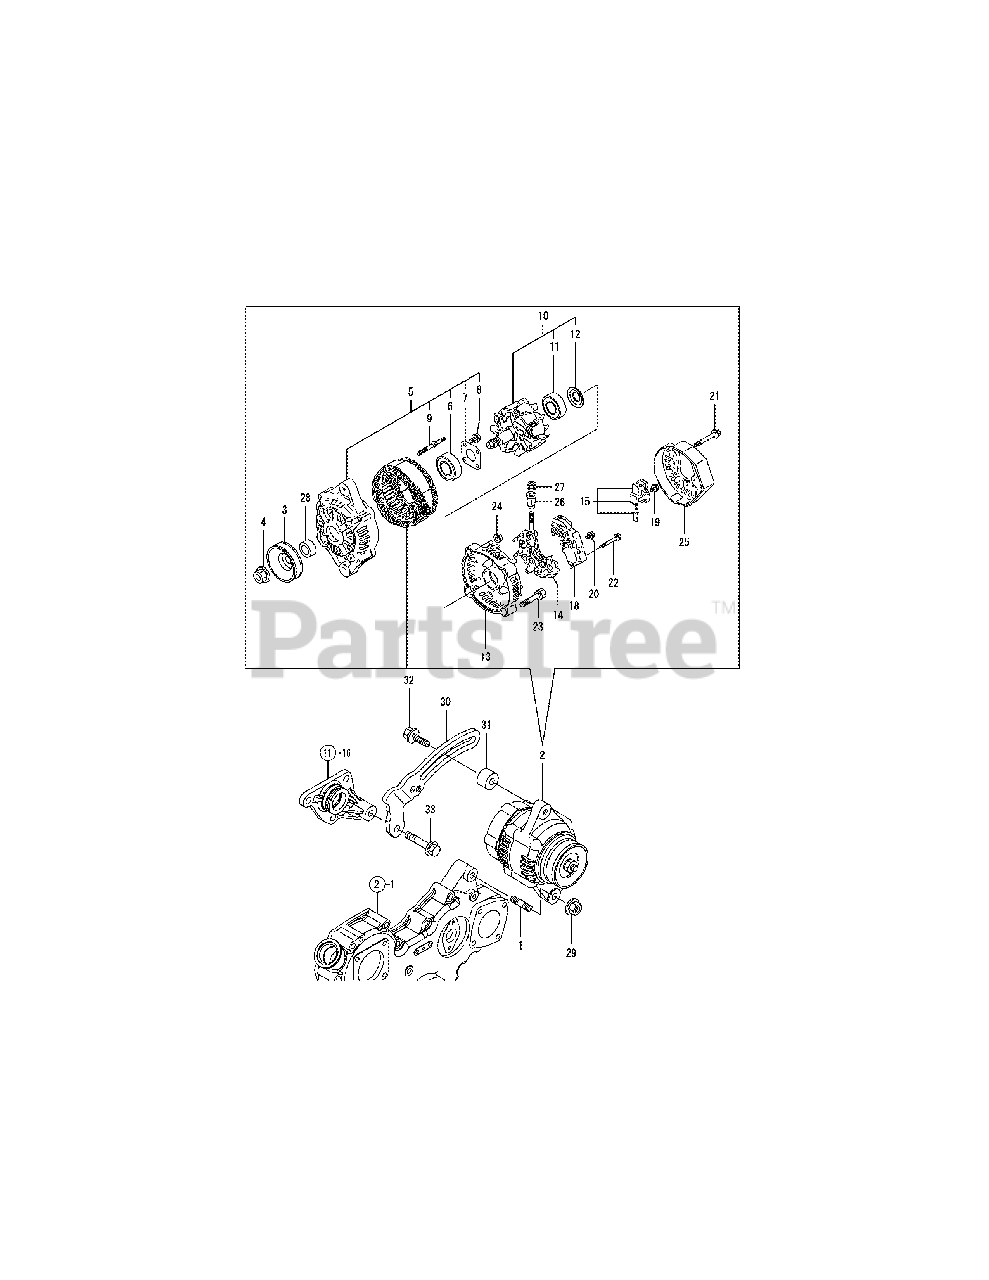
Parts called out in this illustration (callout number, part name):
2	GENERATOR 12V-40A
12	COVER, BEARING
13	FLAME ASSY, REAR
18	REGULATOR ASSY
22	SCREW W/WASHER
26	INSULATION BUSH
32	BOLT, ADJUSTING
33	BOLT M 8X 50 PLATED
